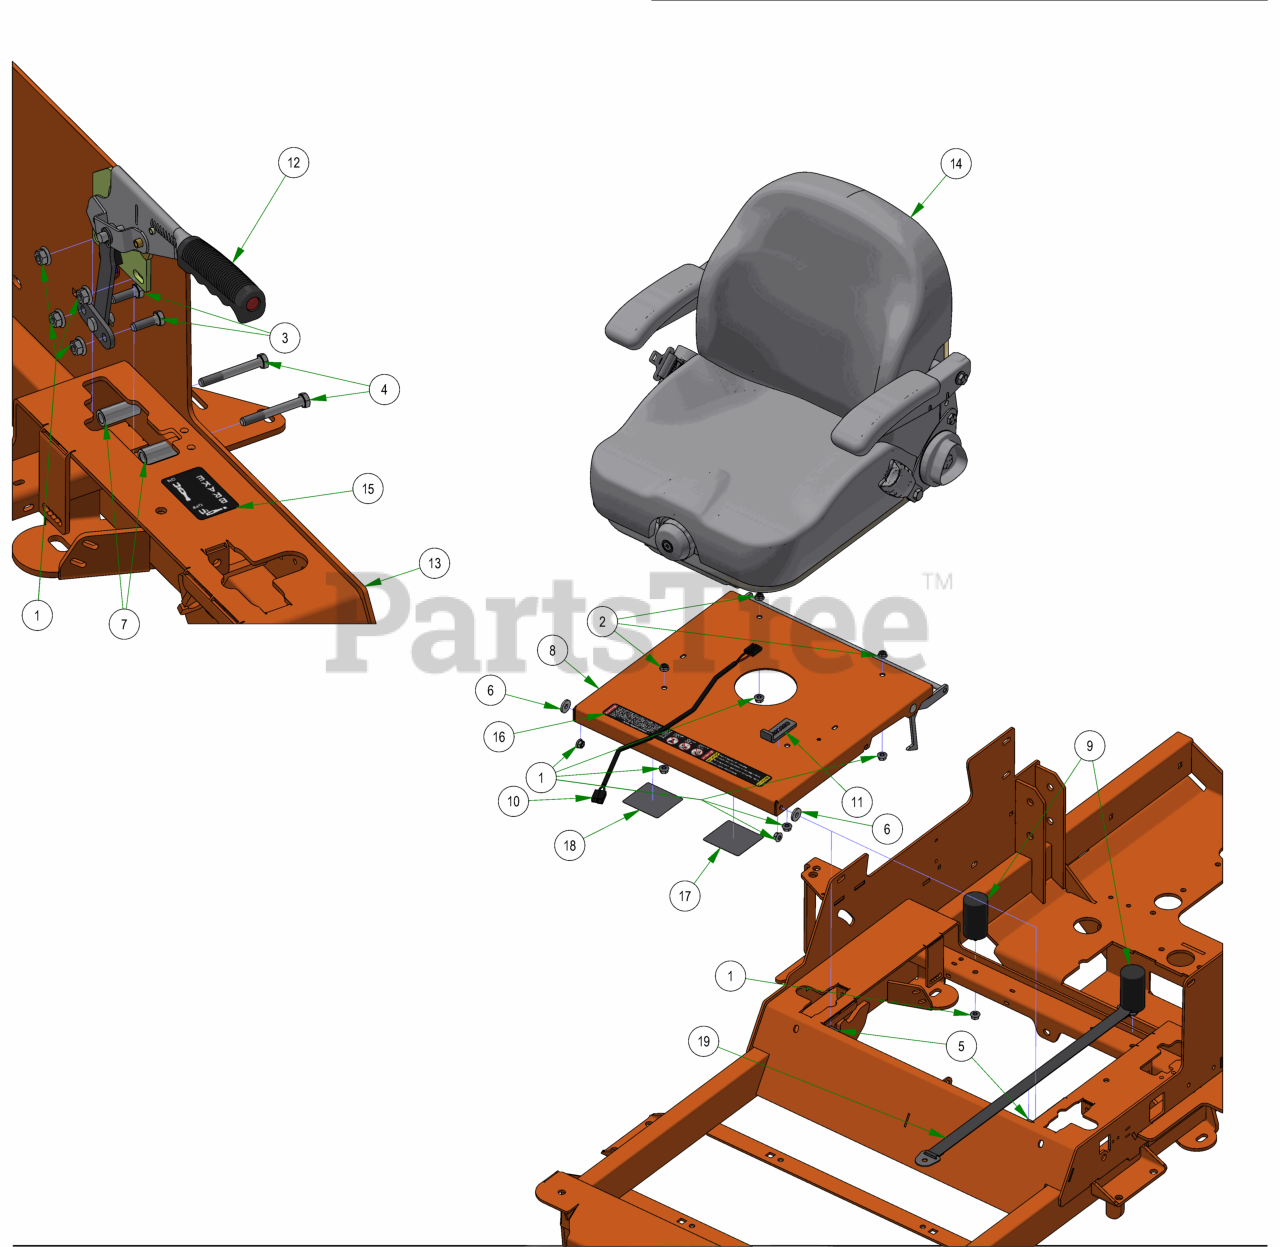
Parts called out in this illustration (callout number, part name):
1	5/16-18 NYLON INSERT FLANGE LOCKNUT ZINC
2	5/16-18 HEX SERRATED FLANGE NUT HARD/ZINC
3	5/16-18 X 1 HEX CAP SCREW (GR.5) ZINC
4	5/16-18 X 2-1/2 HEX CAP SCREW (GR.5) ZINC
5	5/16-18 X 1 CARRIAGE BOLT (GR.8) ZINC
6	.360 ID X .983 OD X .120 THICK FLAT WASHER NYLON
7	.380 ID X .625 OD X 1.500 LGTH 2019 OUTLAW BRAKE HANDLE SPACER ZINC
8	R-SERIES SEAT PLATE ASSEMBLY
9	2019 Bad Boy X Cylindrical Seat Mount
10	Seat Switch Adapter
12	2019 Brake Handle Assembly
13	2022 Horizontal Diesel Frame
14	2025 Seats Inc Suspension
15	2018 Out/XP/Diesel Brake Decal
16	Outlaw Warning Decal
17	Control Adj. Control Rod Decal
18	Control Adj. Control Dampener Decal
19	Seat Strap with Buckles
